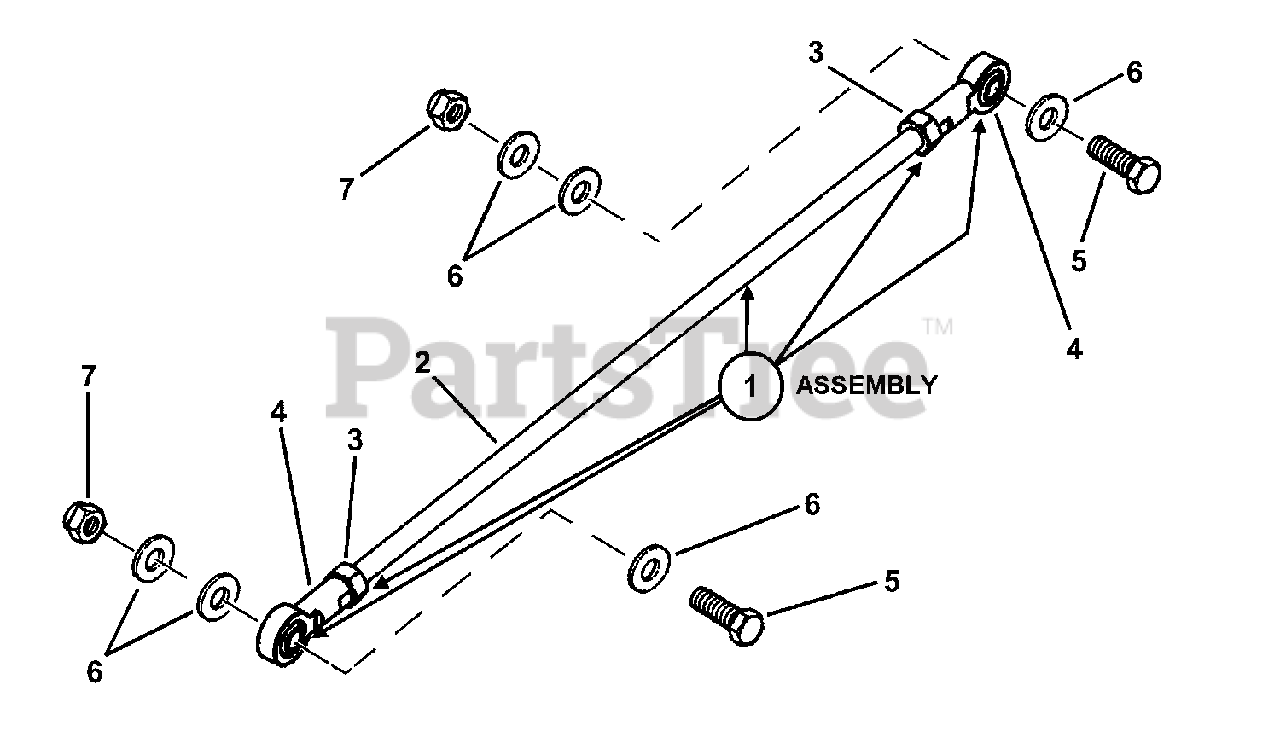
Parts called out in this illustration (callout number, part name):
1	ASSEMBLY, Pump Control Linkage
2	LINKAGE ROD, Pump Control (5/16-24 thread- both ends)
3	NUT, 5/16-24 Hex GR 5
4	BALL JOINT, 5/16-24
5	BOLT, 5/16-18 X 1-1/4 GD5 YZ
6	WASHER, 5/16" Flat
7	NUT, 5/16-18 HEX NYLON LOCK
